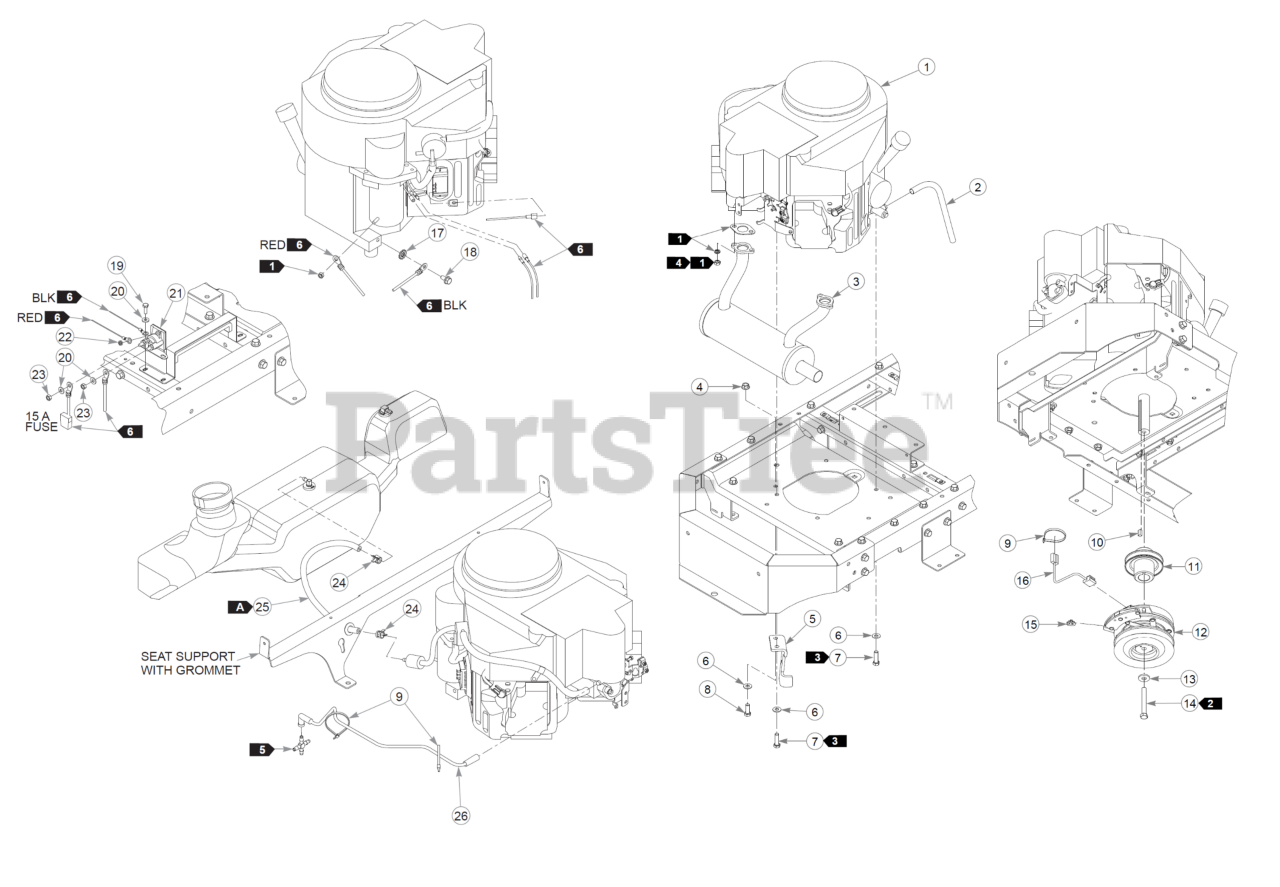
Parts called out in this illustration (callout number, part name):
2	HOSE, OIL DRAIN
3	MUFFLER, FR730V
4	NT .375-16 FLKG5
5	CLUTCH ANCHOR
6	FW 0.379X.82X.06 HD ZN
7	CS .375-16X1.25HXG8ZYP85
8	CS .375-16X1.00 HX G5 ZN
9	WIRE TIE, SMALL/SHORT
10	KEY 1/4 SQ X 0.66 LG(FS)
11	PULLEY, ENG 4.118 OP
12	CLUTCH KIT, 605777
13	FW .453X1.12X.12 HRD ZN
14	CS .437-20X3.25 HXG5 P85
15	BUSHING, CLUTCH
16	HARNESS, CLUTCH PIGTAIL
17	LW .312 INTEXT ZN
18	CS M8-1.25X16HX FL10.9
19	CS .250-20X0.75 HX G5 ZN
20	FW 0.281SAE
21	STARTER SOLENOID
22	NT #10-32HXG5
23	NT .250-20HXG5
24	CLIP, HOSE CLAMP
25	FUEL LINE, 1/4"
26	VAPOR LINE, 3/16 FORMED
